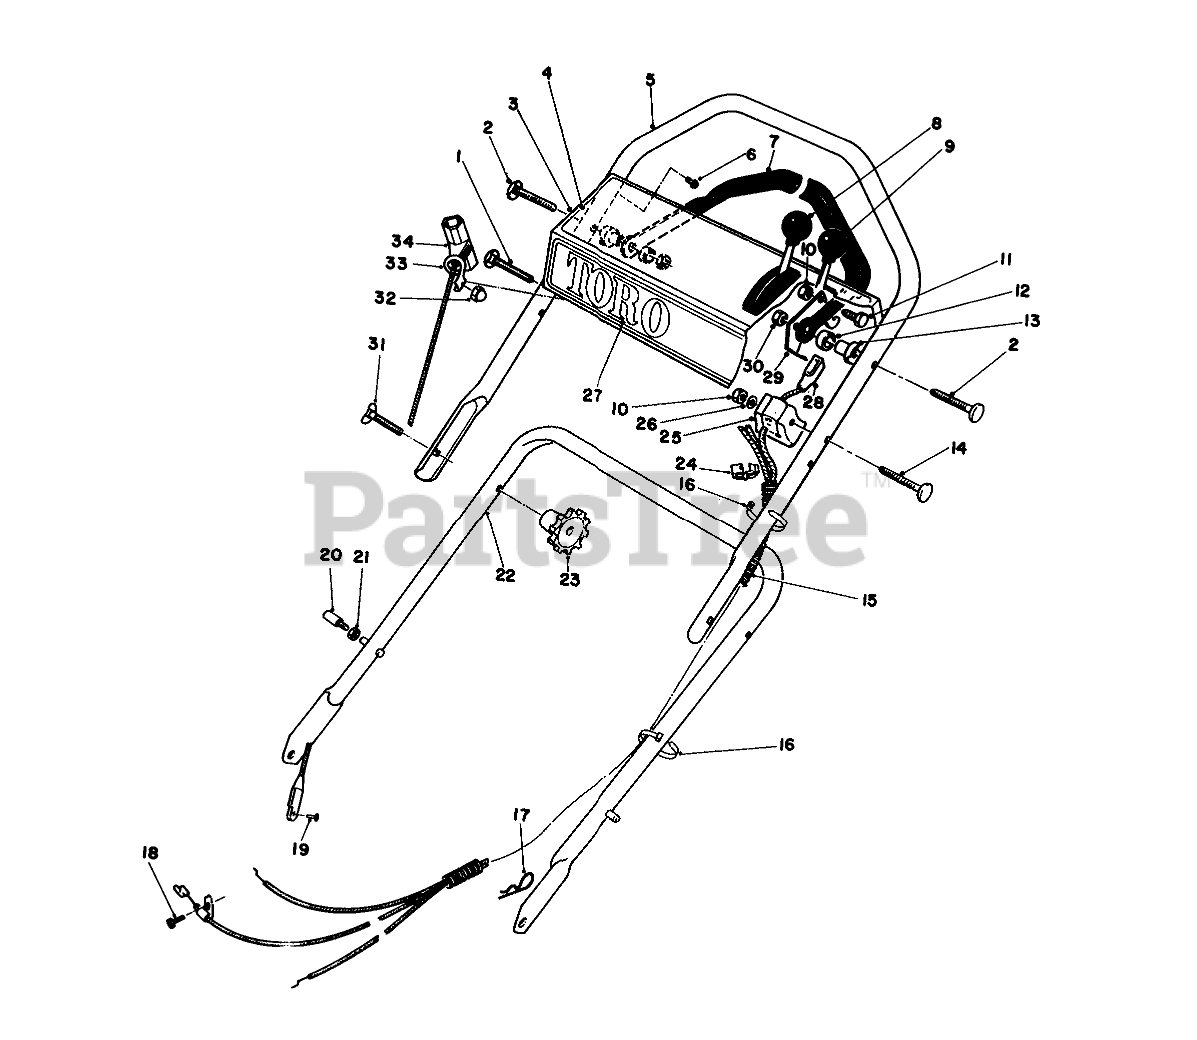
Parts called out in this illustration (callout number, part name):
1	HANDLE SCREW
2	5/16-18 X 2 HNDLE SCREW
3	Panel-Control (Incl. Ref. #4)
4	Decal-Instruction
5	Handle-Upper
6	SCREW-HWHTF
7	Bar-Control
8	SERVICE THROTTLE CONTRO
9	SERVICE TRACT. CONTROL
10	NUT-LOCK, NI
11	SCREW-HH
12	SPACER-NYLON
13	SPACER-SUPPORT
14	SCREW-HANDLE
15	CONT. CABLE COVER
16	TIE-CABLE
17	PIN-COTTER, HAIR
18	SCREW-HH
20	HANDLE PIN
21	NUT-LOCK, NI
22	LOWER HANDLE ASM
24	FITTING-RING
25	SUPPORT-CABLE
26	WASHER-FLAT
27	Decal-Toro
28	BRAKE CABLE
29	Lever-Control
30	NUT-LOCK, NI
31	5/16-18 X 2 HNDLE SCREW
32	NUT-CAP
33	Guide
34	Rope-Starter
